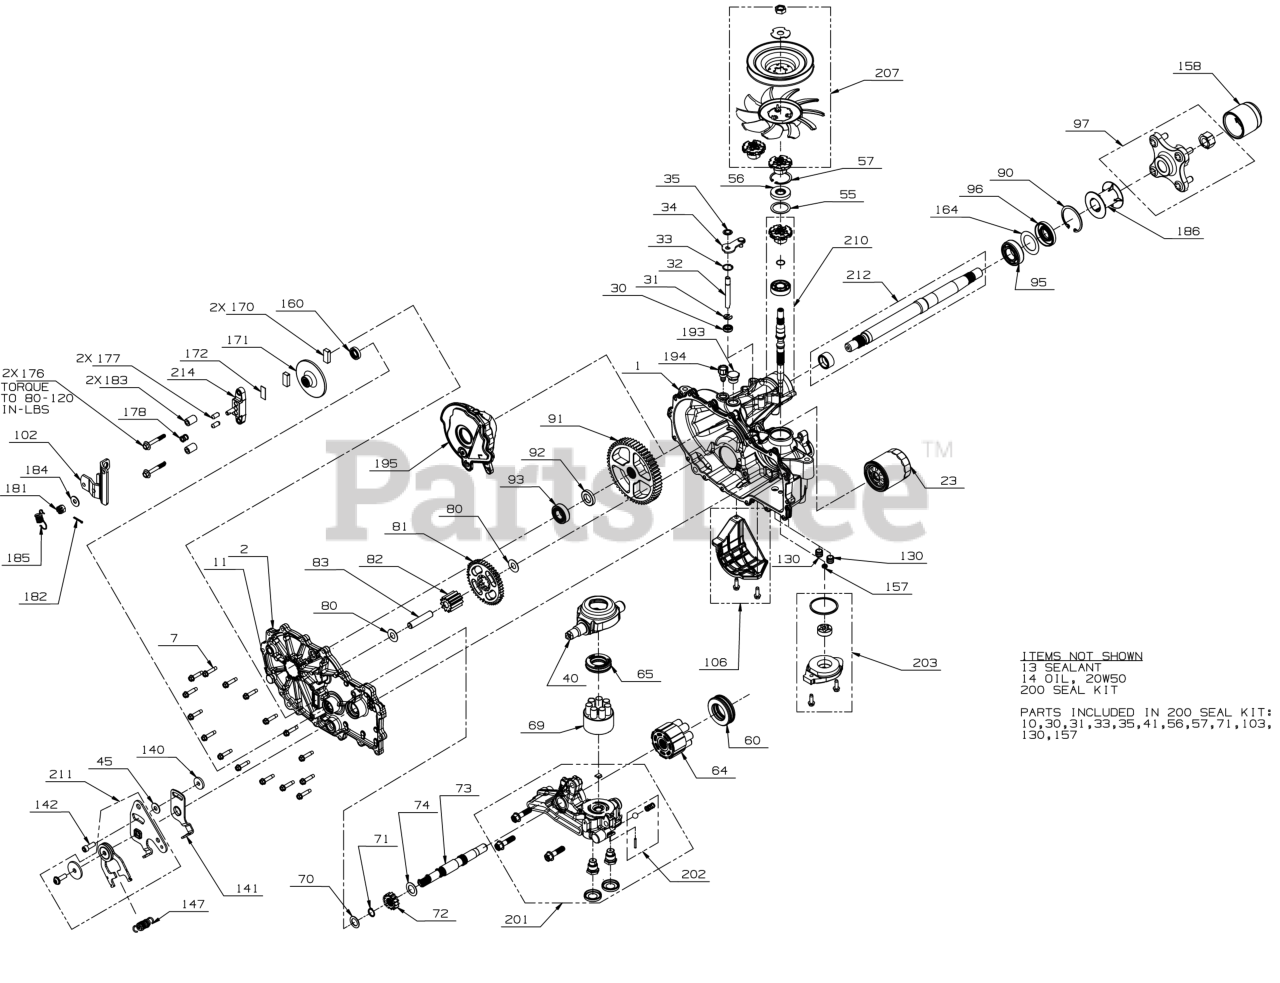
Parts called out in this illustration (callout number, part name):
1	MAIN HOUSING KIT (LH)
2	SIDE COVER KIT (LH)
7	SCREW-WASHER HEAD
11	VENT PLUG
13	SEALANT-HOUSING
23	OIL FILTER
30	SEAL-LIP .375 X .75 X .25
31	RETAINING RING
32	BYPASS RODS
33	RETAINING RING
34	ARM-BYPASS
35	RETAINING RING
40	SWASHPLATE-TRUNNION
45	FLAT WASHER
55	WASHER 1.23X1.56X
57	RETAINING RING
60	THRUST BEARING
64	CYLINDER BLOCK ASSEMBLY
65	THRUST BEARING
69	BLOCK KIT-7 PISTON
70	FLAT WASHER
71	RETAINING RING
73	MOTOR SHAFT
74	MOTOR SHAFT WASHER
81	GEAR-45T JACK SHAF
82	GEAR-11 T
83	PIN-JACKSHAFT
90	RETAINING RING
91	GEAR-54 T
92	SPACER .75X1.32X.257
93	BALL BEARING
95	BALL BEARING
97	HUB KIT-4 BOLT
102	ARM-BRAKE
106	FILTER GUARD KIT
130	TUBE-CHARGE TRIPLE O-RING
140	SPACER .32 x 1.005 x .179
141	ARM-NEUTRAL (RH)
142	SCREWS KIT-RTN
147	EXTENSION SPRING
157	KIT-GEROTOR SEAL
170	BRAKE PUCK
171	ROTOR-BRAKE
172	PUCK PLATE
176	BOLT-SPECIAL FLANG
177	ACTUATING PIN
178	BRAKE SPRING
182	COTTER PIN-3/32 DIA x .75
183	SPACER-TORSION SPG
184	FLAT WASHER
185	BRAKE SPRING
186	TUBE-AXLE 2.03
193	PLUG 3/4-16
194	BREATHER FITTING 9/16-18
195	EXPANSION TANK (LH)
201	CENTER SECTION KIT (LH)
202	KIT-CHARGE RELIEF
203	CHARGE KIT
207	FAN & PULLEY KIT
209	PULLER KIT-HUB
210	INPUT SHAFT KIT
211	RETURN KIT-NEUTRAL (RH) ZT2800 RZT
212	SHAFT KIT-AXLE
214	BRAKE YOKE ASSEMBLY
